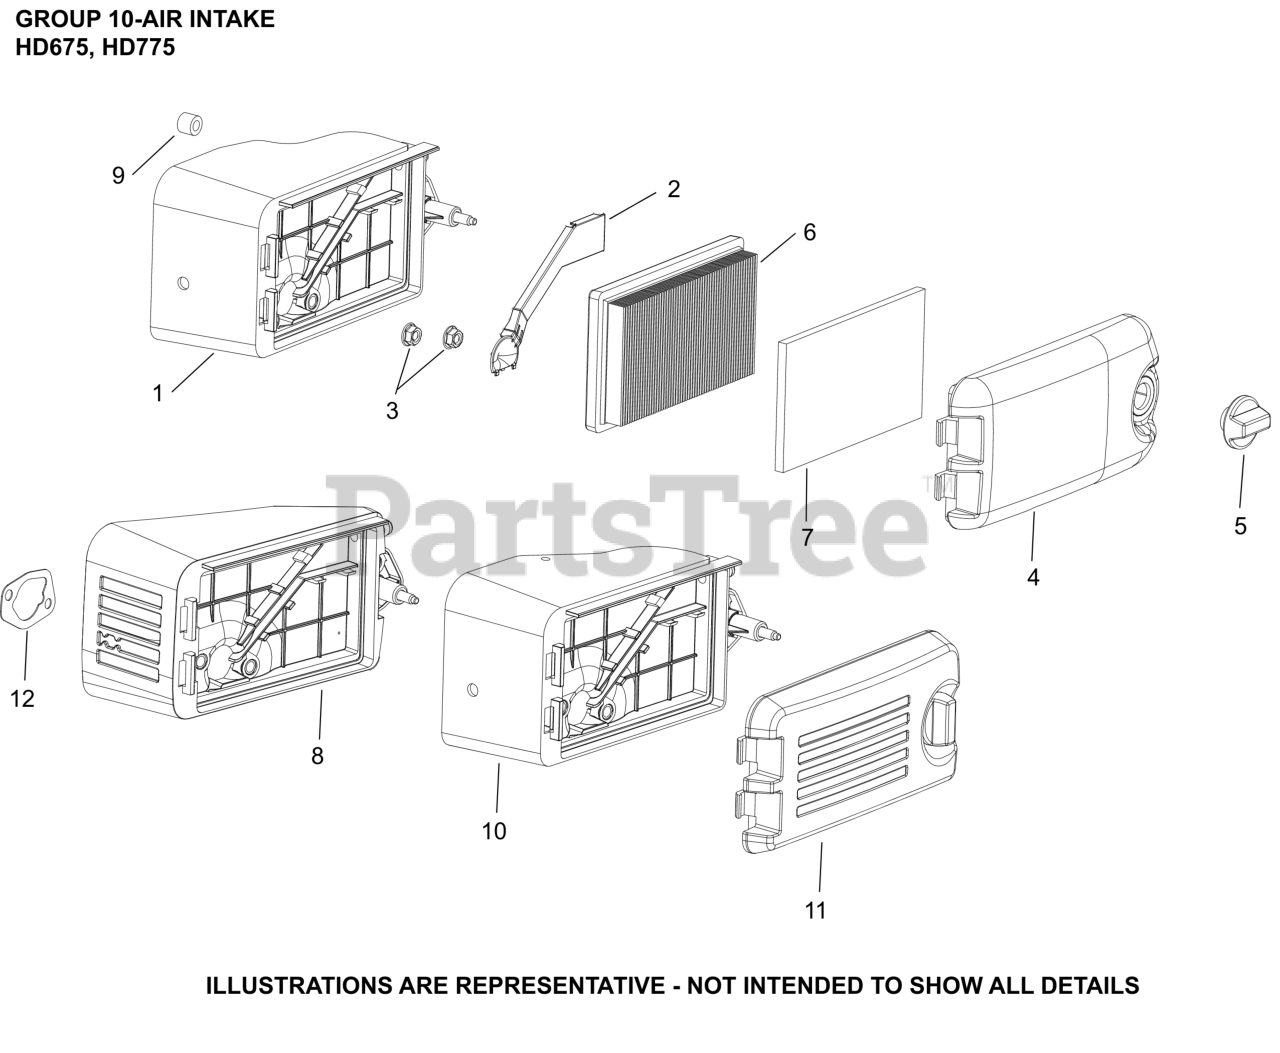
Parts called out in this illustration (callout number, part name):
1	KIT, AIR CLEANER BASE
2	COVER, A/C BASE (BREATHER GAS)
4	COVER, AIR CLEANER
5	KNOB-USE 14 341 07-S
6	ELEMENT, AIR FILTER
7	ELEMENT, PRE-CLEANER
